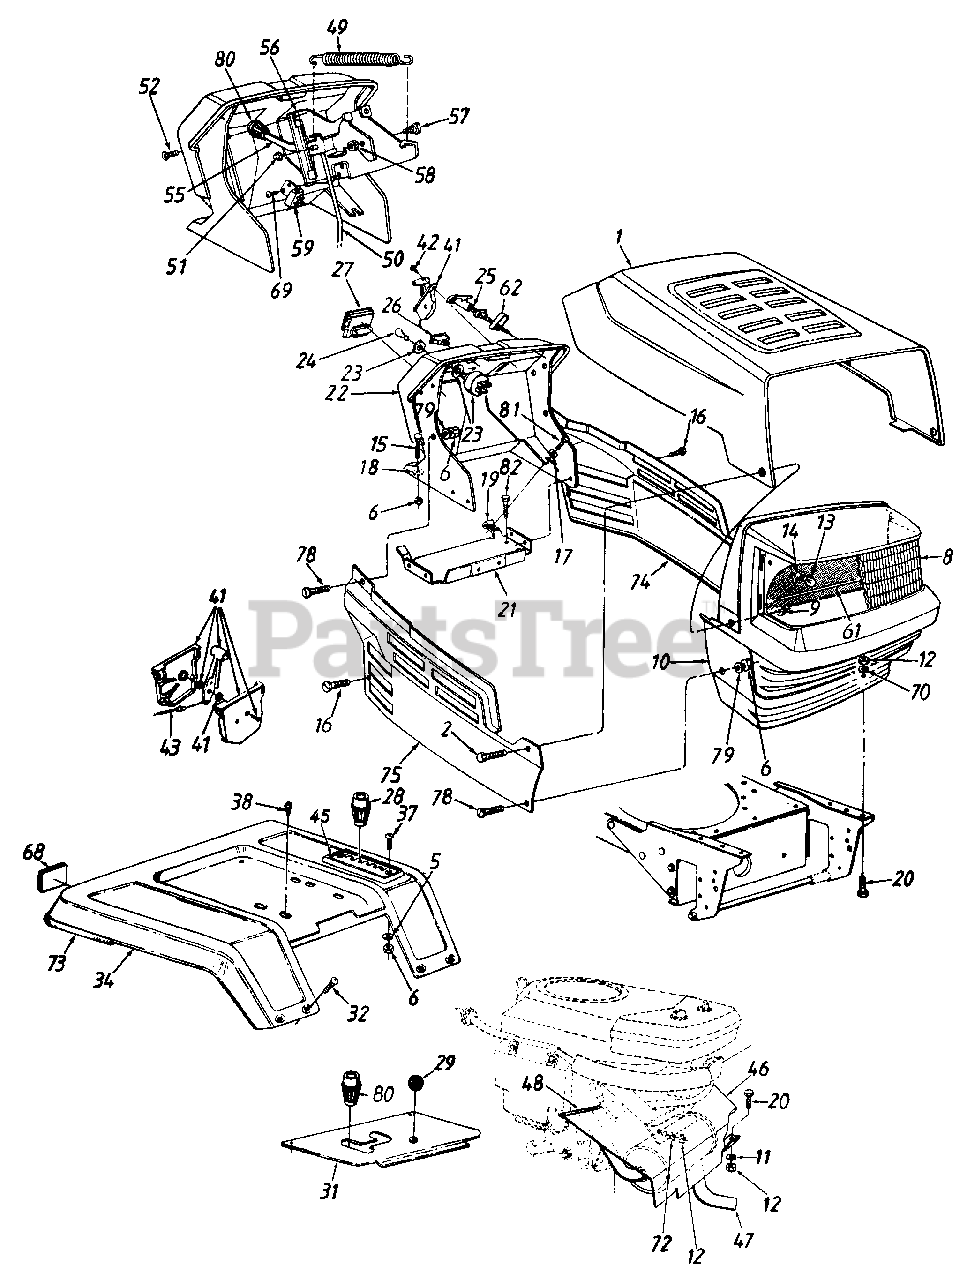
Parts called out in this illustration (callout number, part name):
5	L-Wash. 1/4" I.D.
6	Hex Nut 1/4-20 Thd.
8	Headlight Lens
9	Flange L-Nut 1/4-28 Thd.
10	Grille
11	L-Wash. 5/16" I.D.
12	Hex Nut 5/16-18 Thd.
13	Lamp
14	Socket
15	Carriage Bolt 1/4-20 x 1.0" Lg.
16	Hex Wash. Hd. TT-Tap Scr. 1/4-20 x .5" Lg.
17	Fl-Wash. .281" I.D. x .73" O.D.
18	Bolt Retainer 1/4" I.D.
19	Speed Nut 1/4-20 Thd.
20	Hex Bolt 5/16-18 x .75" Lg.
23	Ignition Switch
24	Ignition Key
25	Choke Control
26	Light Switch
27	Ammeter
28	Shift Knob
32	Carriage Bolt 1/4-20 x .5" Lg.
38	Hex Wash. Hd. AB-Tap Scr. 5/16 x .75" Lg.
41	Throttle Box Ass'y.
42	Truss Mach. AB-Tap Scr. #10 x .5" Lg.
43	Throttle Control Wire
45	6-Speed Selector Plate
46	Front Heat Shield
47	Muffler
48	Trim Strip 12" Lg.
49	Ext. Spring 5.06" Lg.
50	Deck Control Rod
51	Speed Nut 1/4" Rod
52	Torx Mach. Scr. 1/4 x .62" Lg.
55	PTO Lever
56	PTO Bracket
57	Shld. Bolt. 437" Dia. x .162"
58	Hex L-Nut 5/16-18 Thd.
59	Safety Switch (PTO)
61	Grille Reflector Label
62	Retainer Clip
68	Reflector
69	Hex Wash. Hd. B-Tap Scr. #10 x .38" Lg.
70	Fl-Wash. .344" I.D. x 1" O.D.
72	Spec. L-Wash. 5/16" I.D.
73	Trim Strip 81" Lg.
79	Bell-Wash. 1/4" I.D.
80	Small Shift Knob
81	Hex TT-Tap Scr. 1/4-20 x .75" Lg.
82	Hex AB-Tap Scr. 1/4 x .62" Lg.
